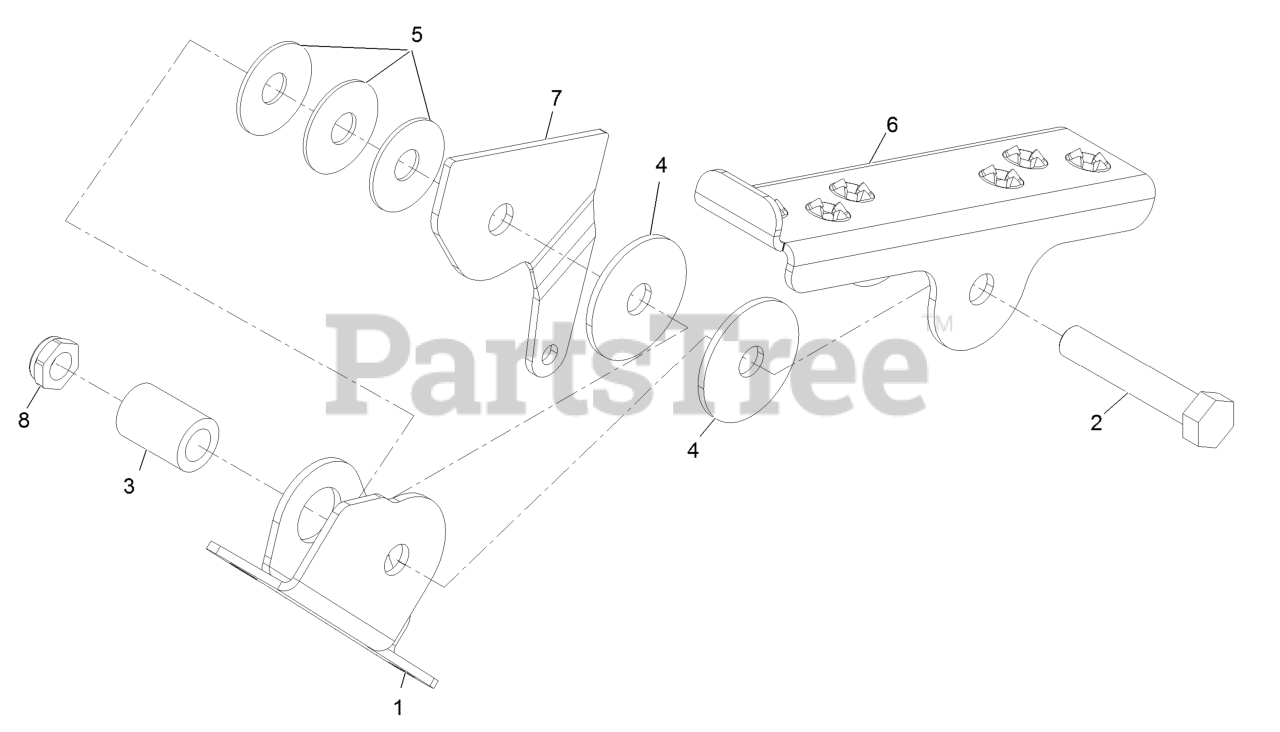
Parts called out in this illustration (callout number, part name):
1	Bracket-Pedal Mount
2	Screw-HH 1/2-13 X 2 3/4
3	Spacer-Roller
4	Disc-Friction
5	Washer-Spring Disc
6	Channel,Pedal Link
7	Arm, Foot Pedal
8	Nut-Nyloc 1/2-13 Thin
